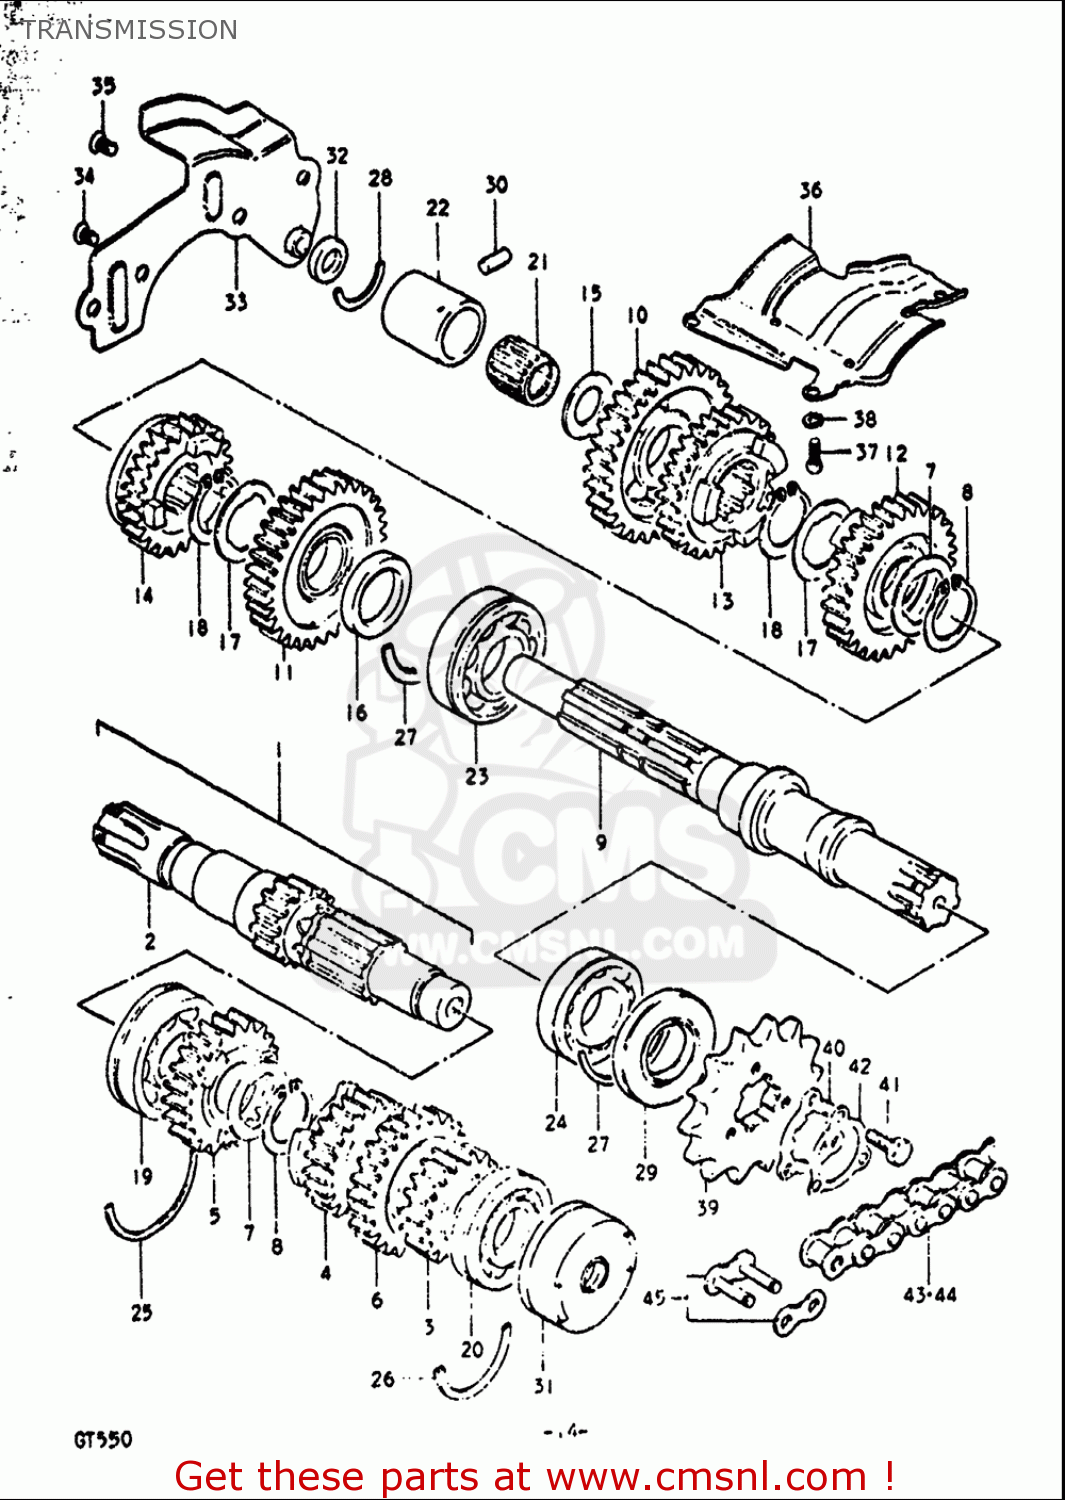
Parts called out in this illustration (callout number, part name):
7	WASHER,LOCK
8	CIRCLIP
15	WASHER (20X30X1)
17	WASHER,LOCK
18	CIRCLIP
20	BEARING(20X47X14)
22	BUSHING
23	BEARING
24	BEARING
25	C RING
26	C RING
27	C RING
28	C RING
30	PIN
32	SEAL,OIL(8X14X4)
34	SCREW
35	SCREW
37	SCREW
38	WASHER,LOCK
39	SPROCKET,ENGINE
40	PLATE,ENGINE SPROCKET
41	BOLT
42	WASHER
